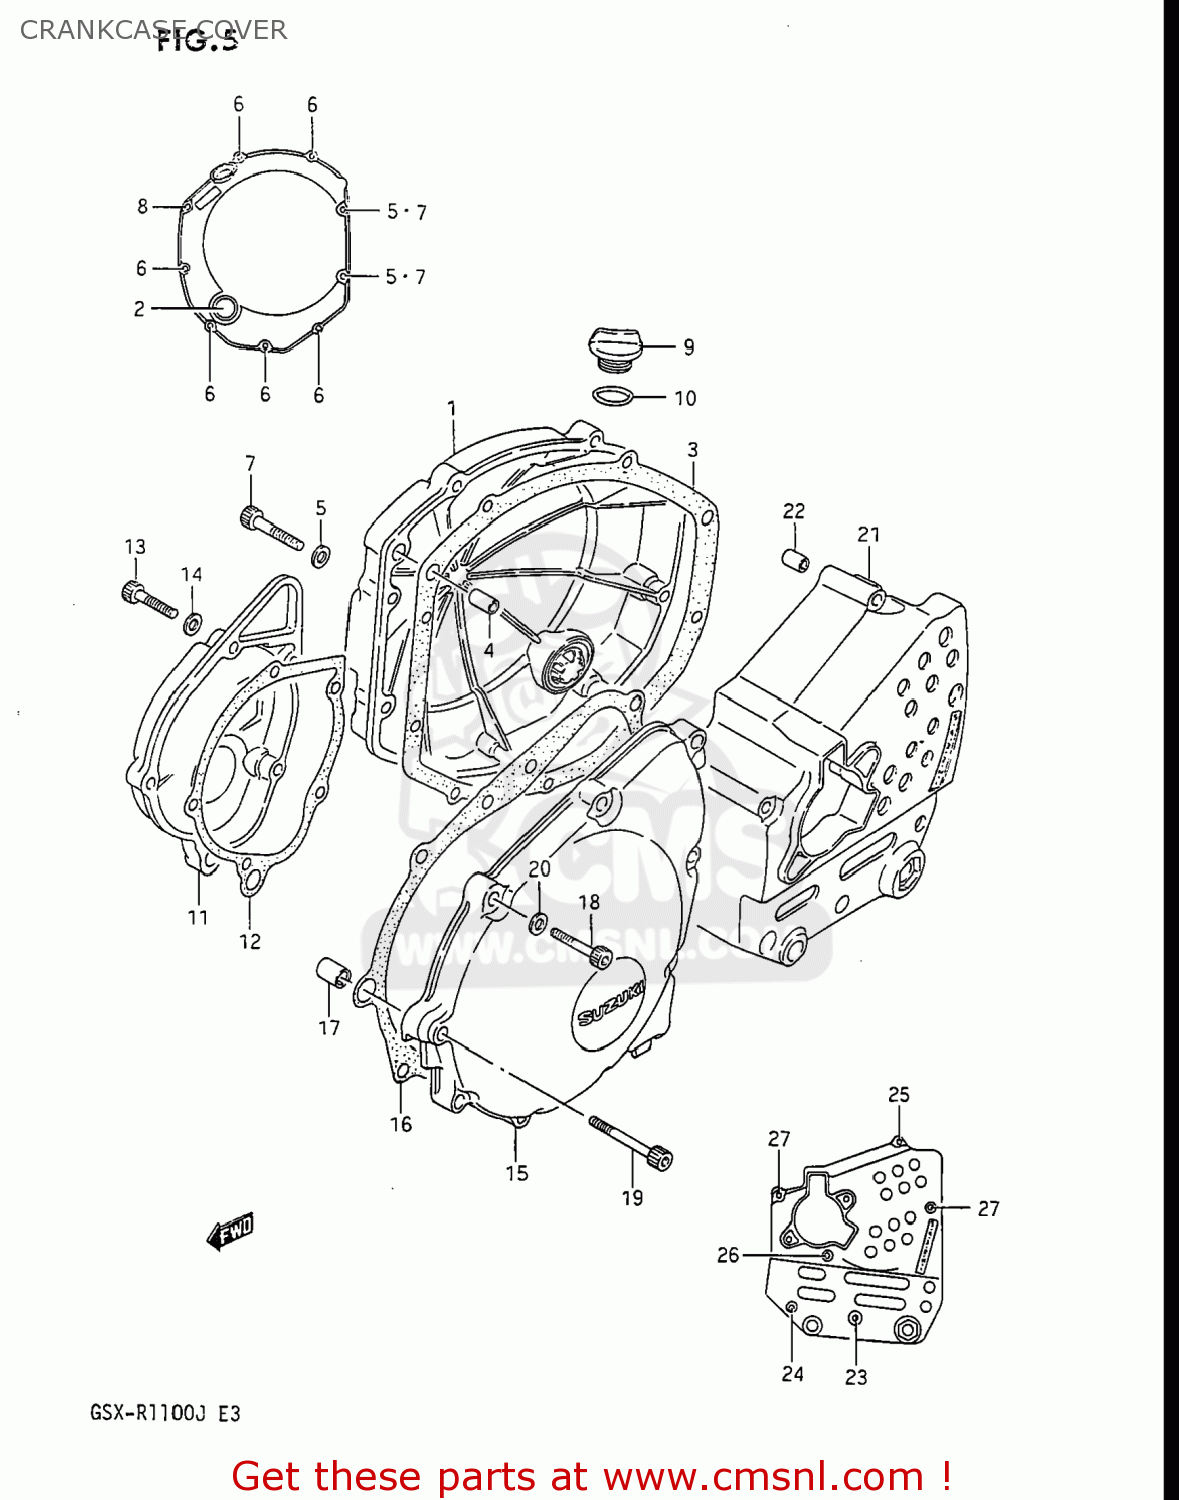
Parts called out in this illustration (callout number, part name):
1	COVER COMP,CLUTCH
2	LENS,OIL LEVEL CHECK
3	GASKET,CLUTCH COVER (MCA)
4	PIN
5	GASKET(5.8X11X1.2) (NAS)
6	BOLT
7	BOLT
8	BOLT
9	PLUG
10	O RING(D:3.1,ID:16.8)
11	COVER,SIGNAL GENERATOR
12	GASKET,SIGNAL GENERATOR COVER (NAS)
13	BOLT
14	GASKET(5.8X11X1.2) (NAS)
15	COVER,STARTER GEAR
16	GASKET,STARTER GEAR COVER (MCA)
17	PIN (11X20)(SUS)
18	BOLT
19	BOLT
20	GASKET(5.8X11X1.2) (NAS)
21	COVER,SPROCKET
22	PIN
23	BOLT
24	BOLT
25	BOLT
26	BOLT
27	BOLT
